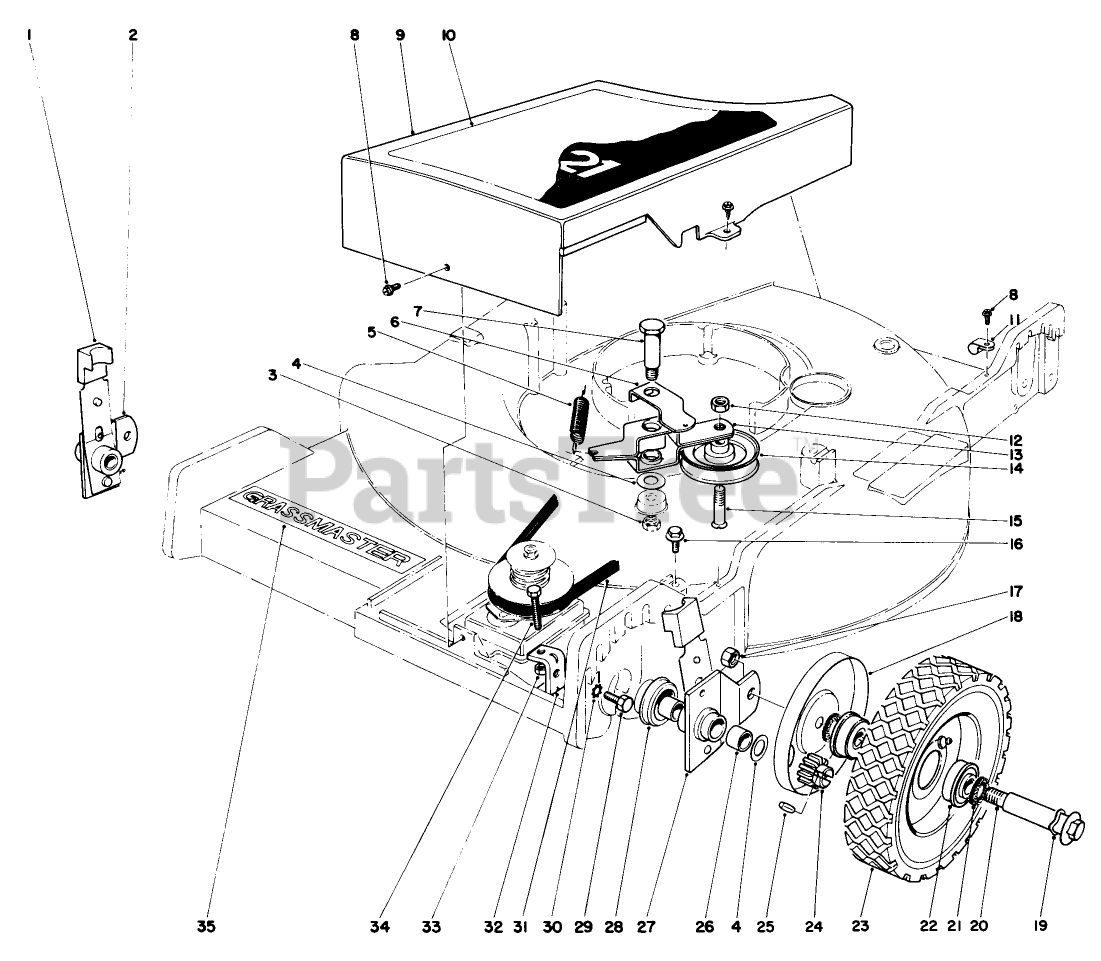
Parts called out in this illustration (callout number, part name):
4	WASHER-THRUST
6	Idler Bracket Lever
7	SCREW-SHOULDER, HH
8	SCREW
10	Decal Belt Cover
11	CLAMP-NYLON
12	NUT-HEX
13	Idler Bracket
15	Screw Low Head
16	SCREW-THD ROLL, HWH
19	SPRING WASHER
20	WHEEL BOLT
22	BEARING-BALL
25	PIN-GROOVED
26	BUSHING
29	SCREW-HH
30	WASHER-LOCK
31	V-BELT
32	Bracket
34	Screw
35	Decal Grassmaster
